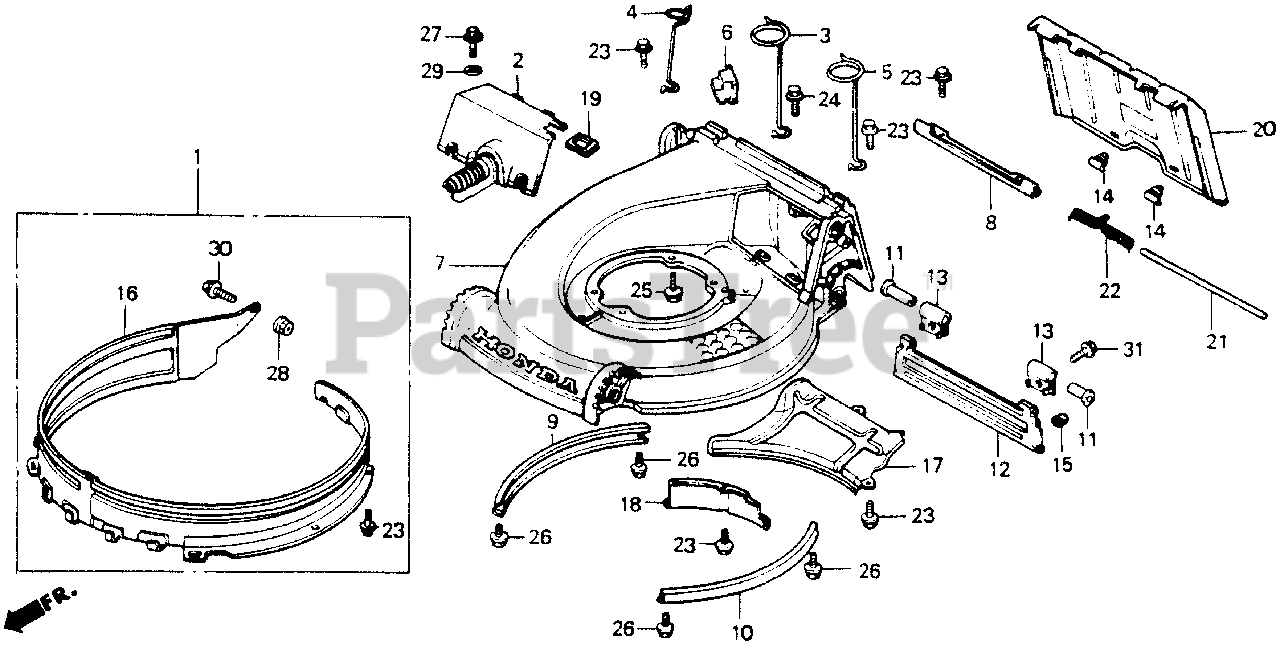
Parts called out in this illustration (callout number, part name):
1	LINER KIT (INNER)
2	COVER, DRIVESHAFT *NH35M* (CLOUD SILVER METALLIC) (NOT AVAILABLE)
3	GUIDE, CABLE
6	GROMMET D, CABLE
7	HOUSING, CUTTER *NH35M* (CLOUD SILVER METALLIC)
8	HINGE, DISCHARGE GUARD
9	GUARD, R. SAFETY
10	GUARD, L. SAFETY
11	BUSH, SAFETY SHIELD
12	SHIELD, SAFETY
13	HANGER, SAFETY SHIELD
14	STOPPER, DISCHARGE GUARD
15	STOPPER, DISCHARGE GUARD Use up to Frame SN 1186736.
16	LINER (INNER)
17	GUIDE, SCROLL
18	LID, ROTO-STOP COVER
19	GROMMET C, CABLE
20	GUARD, DISCHARGE
21	SHAFT, HINGE (NOT AVAILABLE)
21	SHAFT, HINGE
22	SPRING, GUARD RETURN (NOT AVAILABLE)
22	SPRING, GUARD RETURN
23	BOLT, FLANGE (6X12) (CT200)
24	BOLT, FLANGE (6X20) (CT200)
25	BOLT, ENGINE SETTING
26	BOLT, FLANGE (6X10)
27	BOLT, FLANGE (6X25)
28	NUT, FLANGE (6MM)
29	WASHER, PLAIN (6MM)
30	BOLT, FLANGE (6X16)
31	BOLT, FLANGE (6X12)
